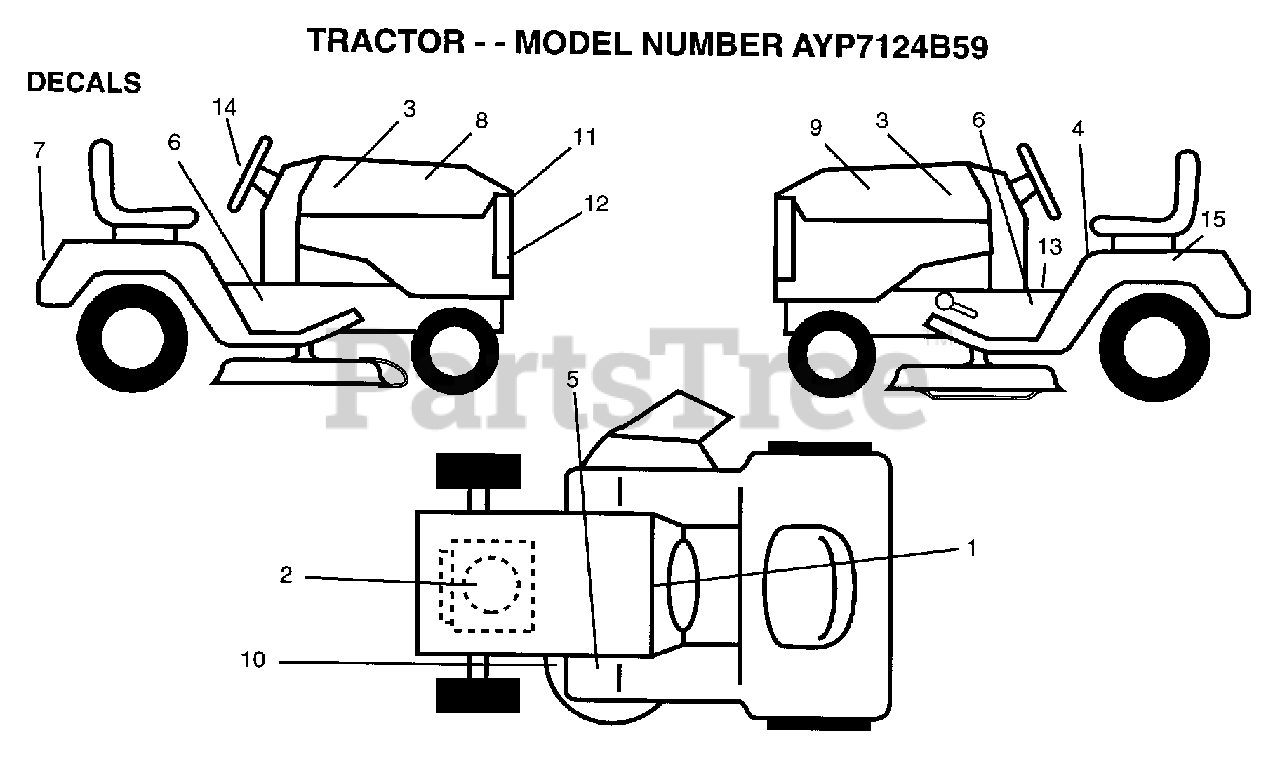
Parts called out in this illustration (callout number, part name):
1	DECAL.DASH.INST.
2	DECAL.ENG.272632
3	NAMEPLATE WIZARD
4	DECAL
6	DECAL CHASSIS
8	DECAL HOOD RH WIZ
9	DECAL HOOD LH WIZ
10	DECAL
11	DECAL GRILL WIZ
12	DECAL GRILL WIZ
13	DECAL BRAK PARK
